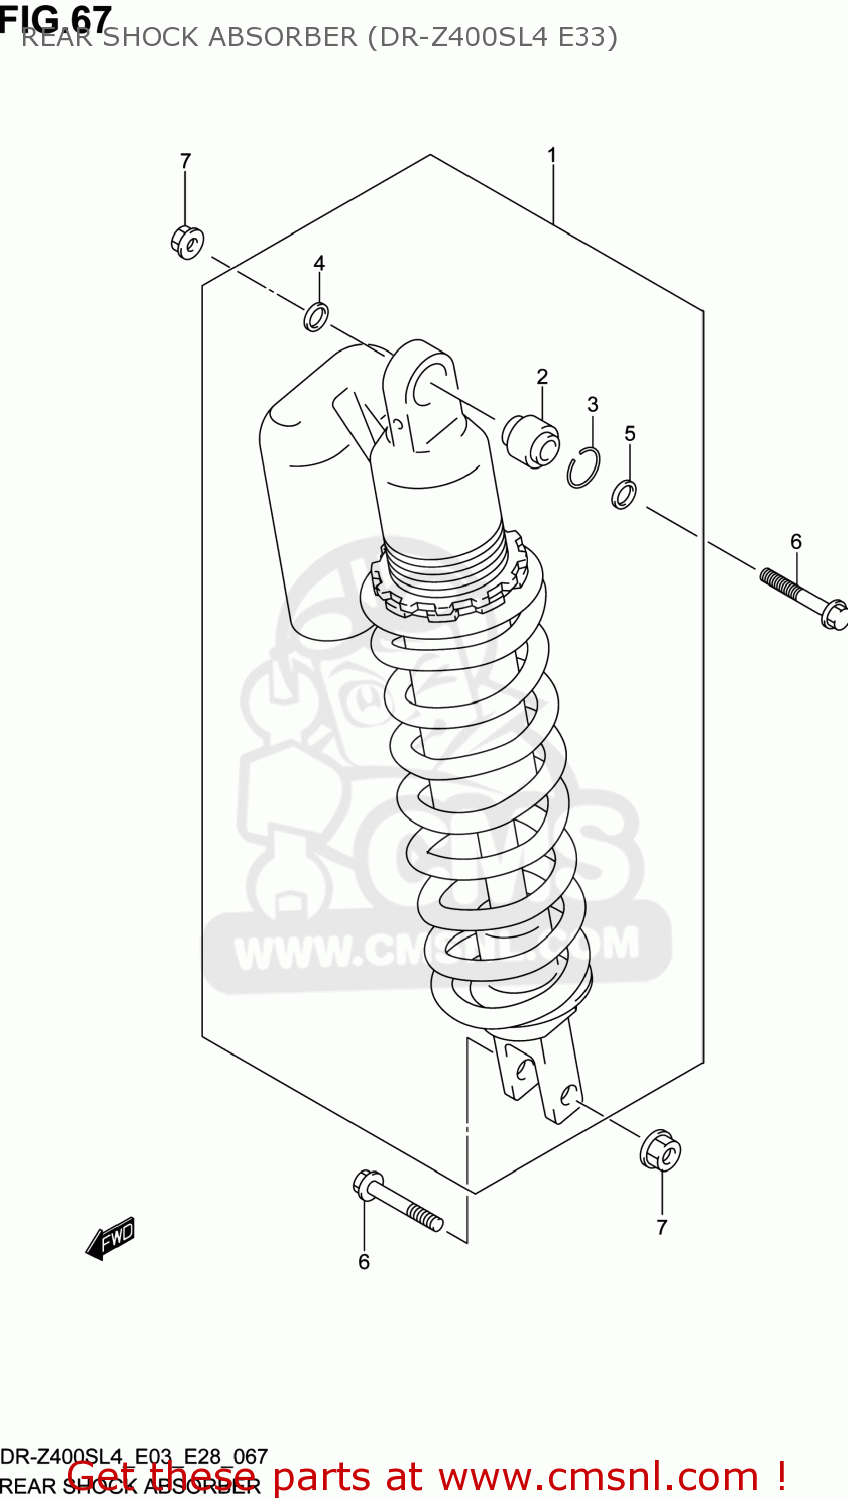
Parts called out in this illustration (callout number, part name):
1	ABSORBER ASSY,RR SHOCK
2	BEARING,RR SHOCK ABSORBER
3	RING,STOPPER
4	SEAL,DUST UPR,R
5	SEAL,DUST UPR,L
6	BOLT(10X47.5)
7	NUT
